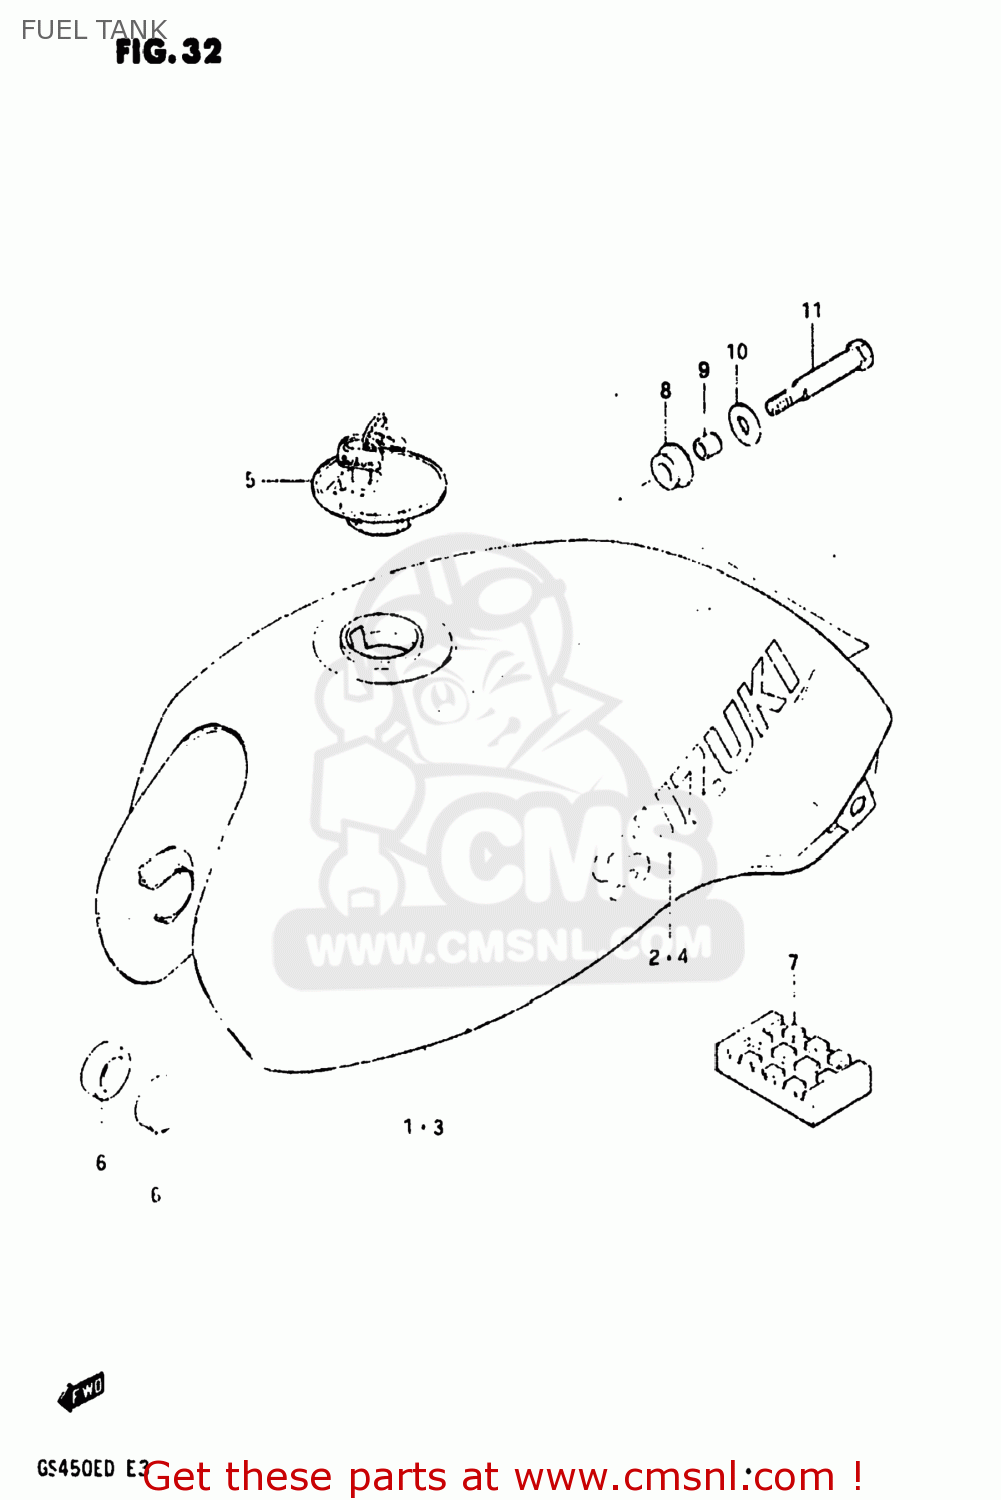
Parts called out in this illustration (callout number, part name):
1	TANK ASSEMBLY,FUEL
2	EMBLEM(SILVER)
3	TANK ASSEMBLY,FUEL
4	EMBLEM(SILVER)
5	CAP SET,FUEL TANK
6	CUSHION
7	CUSHION,FUEL TANK CTR
8	CUSHION
9	SPACER (6.8X10X10)
10	WASHER (6.5X29X1.6)
11	BOLT(6X60)
